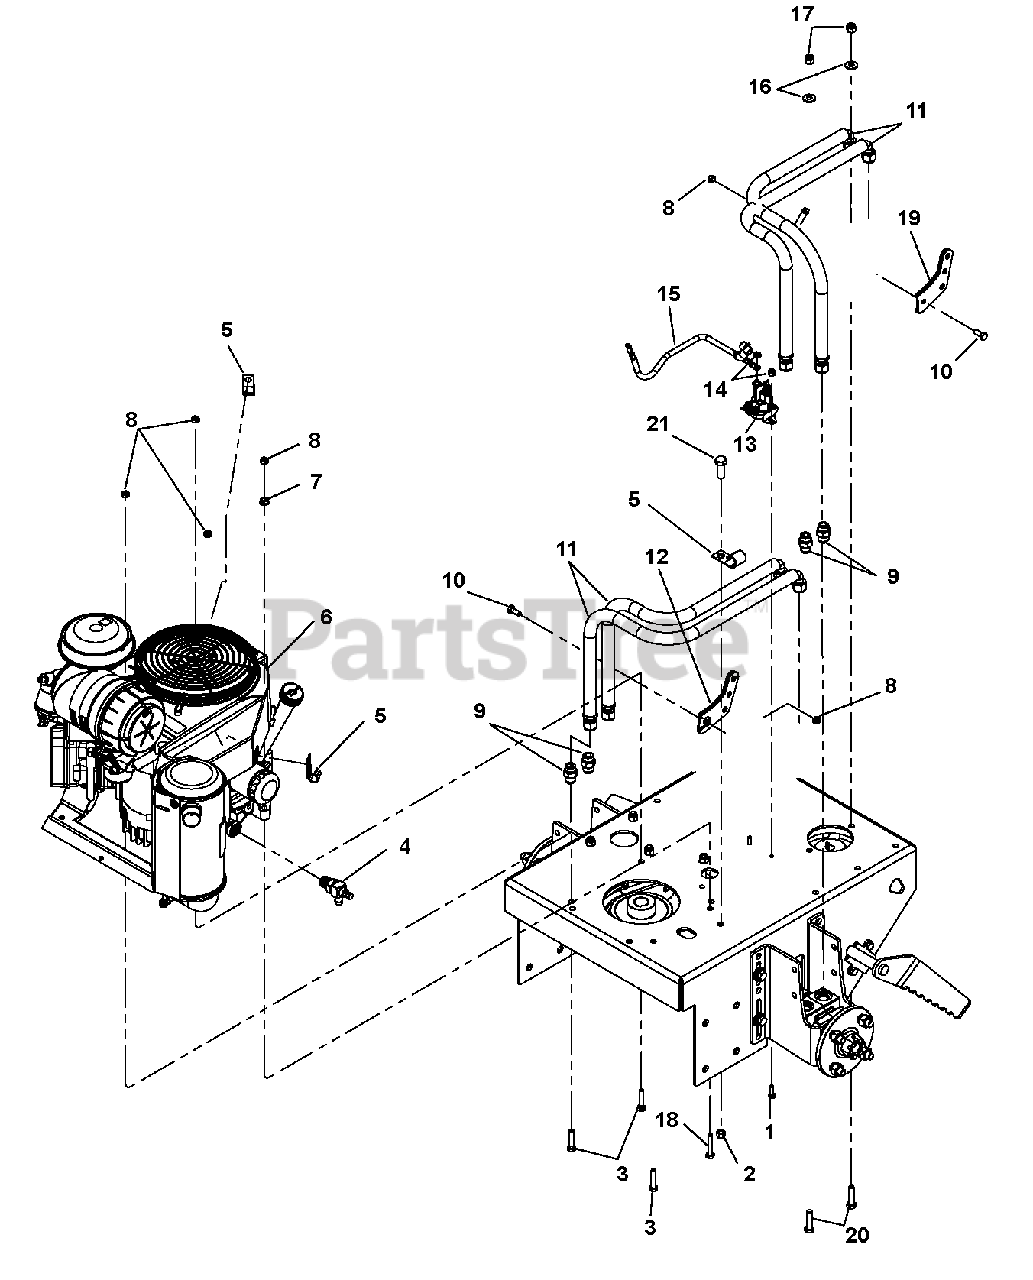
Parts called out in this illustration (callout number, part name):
1	Bolt, Hex .25-20 x .75 Grade 5 (988402, 403)
2	Locknut, .38-16 Nyloc (988400)
3	Bolt, .31-18 x 1.50 Hex Grade 5
4	Fitting, Oil Drain
5	Pillow-Clip, .500 Insulated
6	Engine, Kawasaki 19HP FH580V (988402, 403)
7	Locknut, 5/16-18 WHIZ
8	Locknut, 5/16-18 Nyloc
9	Fitting, Straight
10	Bolt, 5/16-18 x .750 Hex Grade 5
11	Hose, Hydraulic .50 x 26.50 EZFLEx
12	Weldment, CSWS Hydro Pump Arm
13	Solenoid, 12V Starter (988402, 403)
14	Locknut, .25-20 Nyloc (988402, 403)
15	Cable, 12" Starter (988402, 403)
16	Washer, .313 Regular Flat
17	Locknut, .38-16 Nyloc
18	Bolt, .31-18 x 1.75 Hex Grade 5
19	Weldment, CSWS Left Hand Hydro Pump Arm
20	Bolt, .38-16 x 1.50 Hex Grade 5
21	Bolt, .38-16 x 1.00 Hex Grade 5
